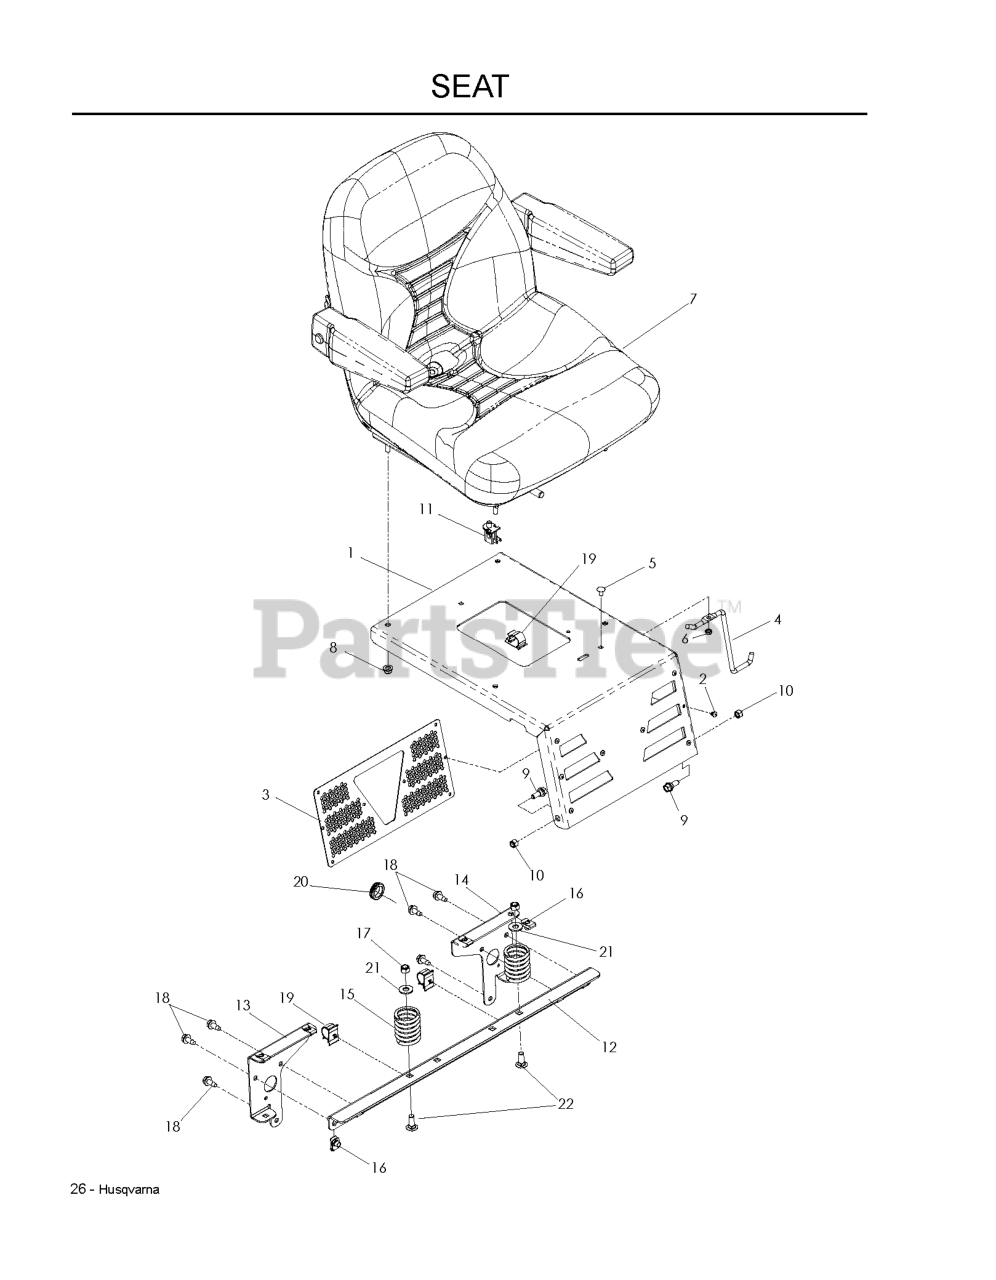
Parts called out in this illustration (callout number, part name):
1	SEAT MOUNT W/DECAL
2	RIVET, 3/16" - .06-.25 GRIP
3	PANEL, HEX
4	STOP, SEAT, FORWQARD
5	RHSSNB 1/4-20 X 1/2
6	JAM NUT 1/4C (2 2 PW01)
7	SEAT
8	5/16-18 NYLOC FLANGE NUT
9	SB 5/16-18 HEX HD GD5, BLK ZN
10	NUT 5/16 NYLOC
11	SEAT SWITCH
12	SUPPORT, SEAT
13	SUPPORT, LT
14	SUPPORT, RT
15	SPRING, SEAT
16	U-CLIP 5/16-18 NUT RETAINER
17	NUT 3/8-16 NYLOC
18	BOLT 5/16-18 X 3/4
19	PUSH-MOUNT WIRE CLIP
20	RUBBER GROMMET
21	WASHER 3/8 FLAT
22	RHSNB 3/8C X 1
